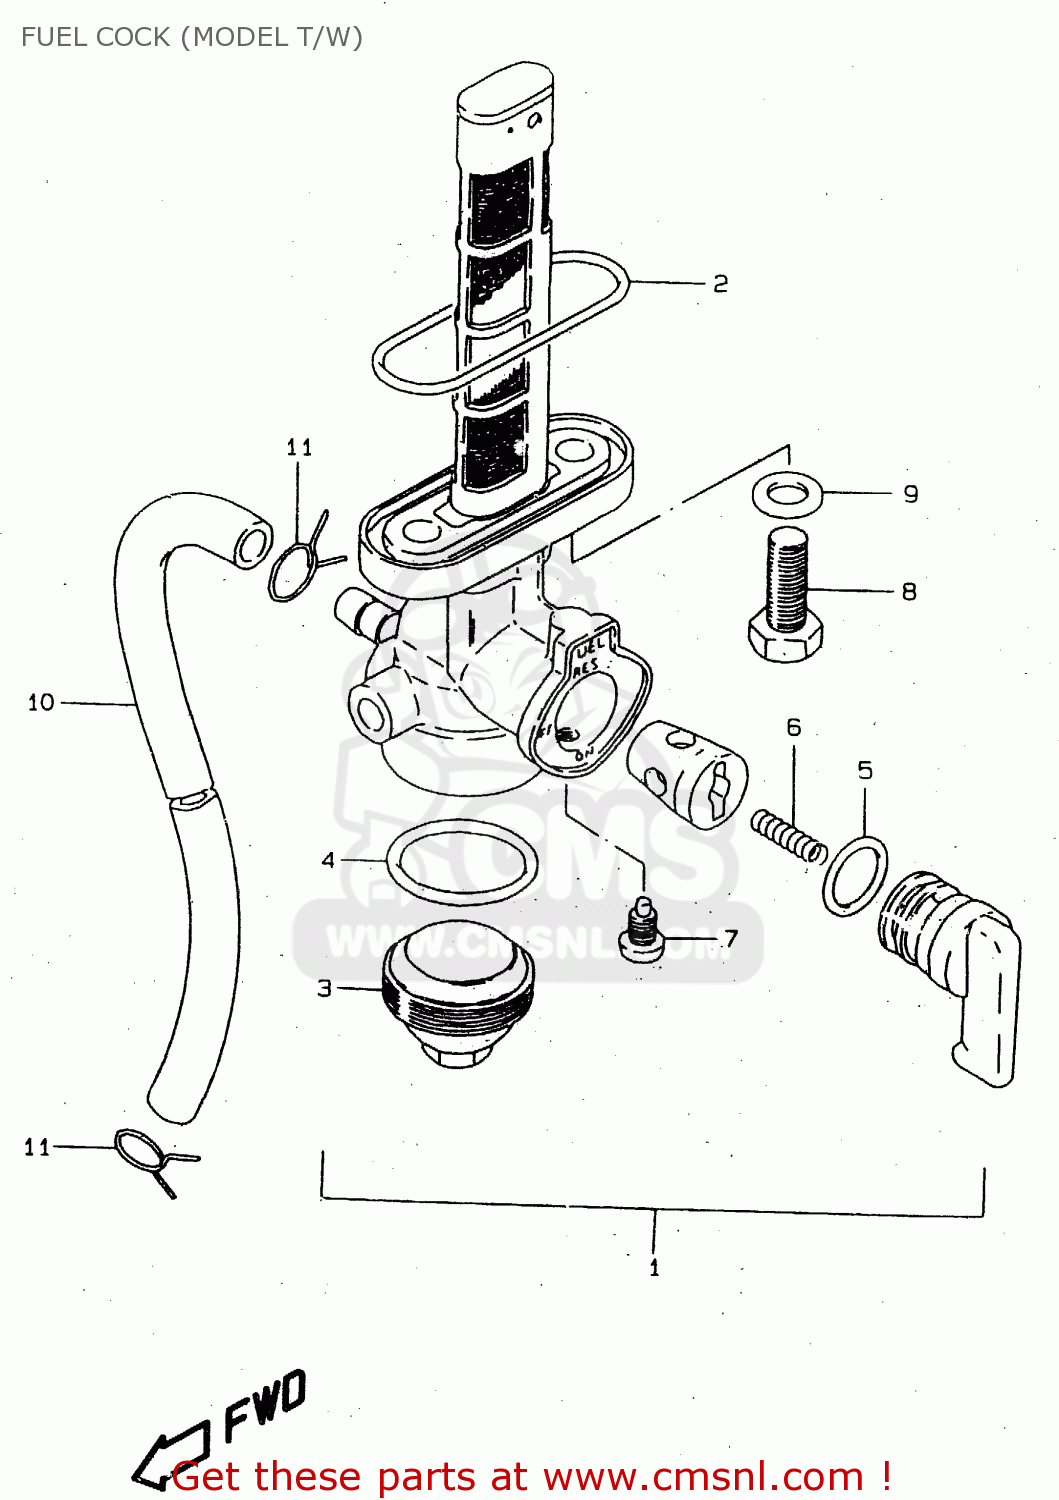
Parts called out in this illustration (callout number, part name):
1	COCK ASSEMBLY,FUEL
2	O RING,FUEL COCK
3	CUP,STRAINER
4	GASKET,FILTER (NAS)
5	O RING,LEVER
6	SPRING
7	SCREW
8	BOLT(6X20)
9	GASKET(6.4X11.5X0.8) (NAS)
10	HOSE(5X8.2X600)
11	CLIP
